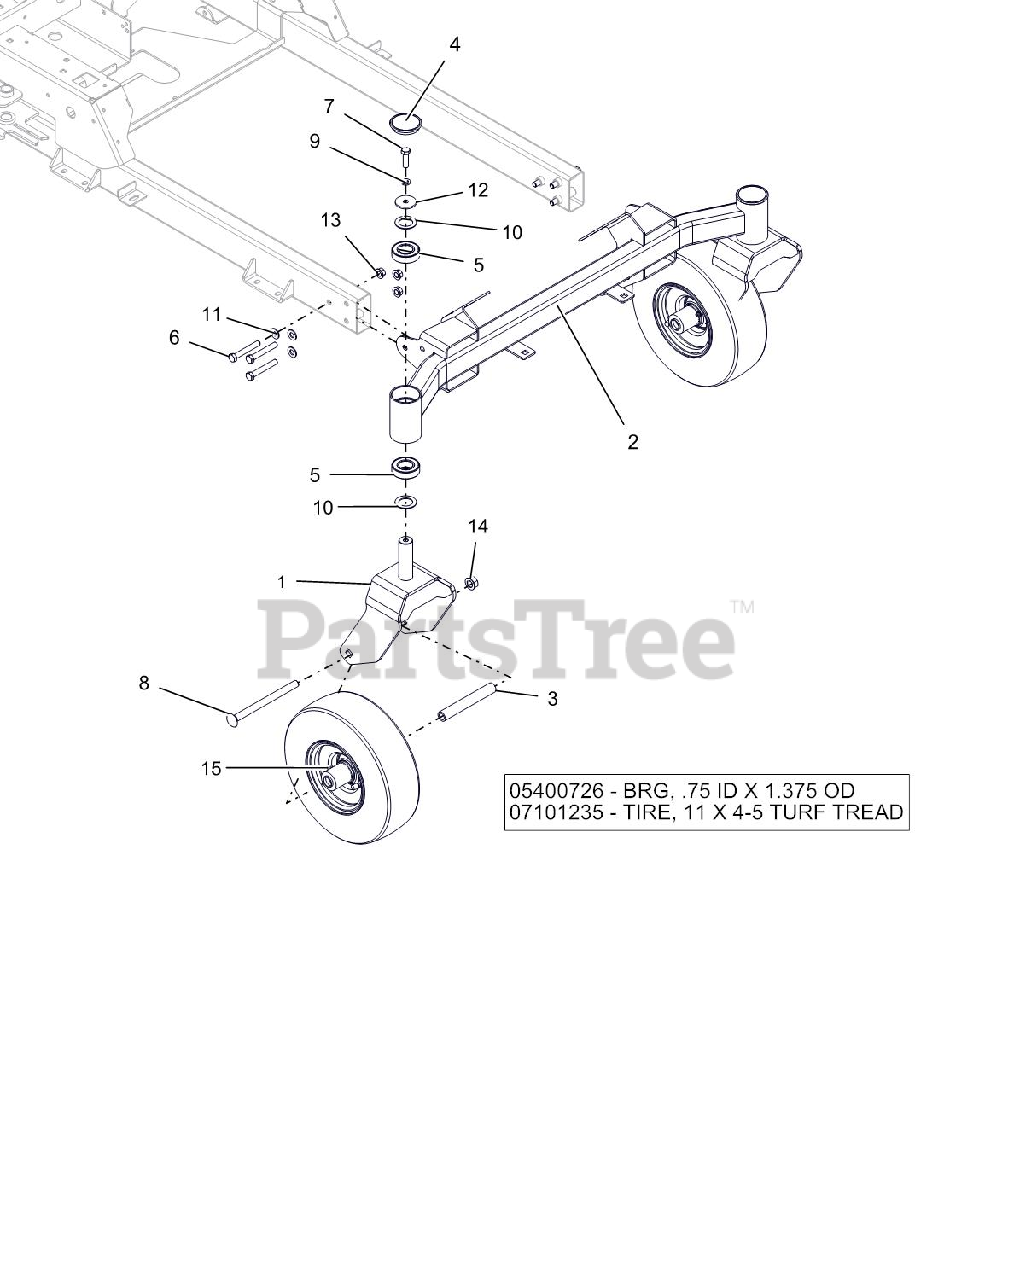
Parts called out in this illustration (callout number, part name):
1	WMT, CASTER FORK
2	WLDMT, AXLE FRONT
3	SPACER, ROLLED WHEEL
4	CAP, DUST
5	BRG,BALL 1.00X2.00X.563(1641)
6	BLT-HEX .38-16X2.50 GR8 YWZC
7	@BLT-HEX .38-16X1.25 GR5 YWZC
8	BLT-RDHDSQNK .50-13X6.50 GR5 Y
9	@WSHR-LK .38X.094 REG YWZC
10	WSHR-HRD-THRS 1.007X1.542X.062
11	WSHR-HDND .406X.812X.055
12	WSHR-FL-STL .380X1.50X.125YWZC
13	NUT-LK-TOP-FLG .38-16 GRG YWZC
14	@NUT-LK-TOP-FLG .50-13 YWZC
15	ASM, WHL/TIRE 11X4.00-5
15	BRG, .75 ID X 1.375 OD
15	TIRE, 11X4-5 TURF TREAD
15	TUBE 11 X4.0-5
